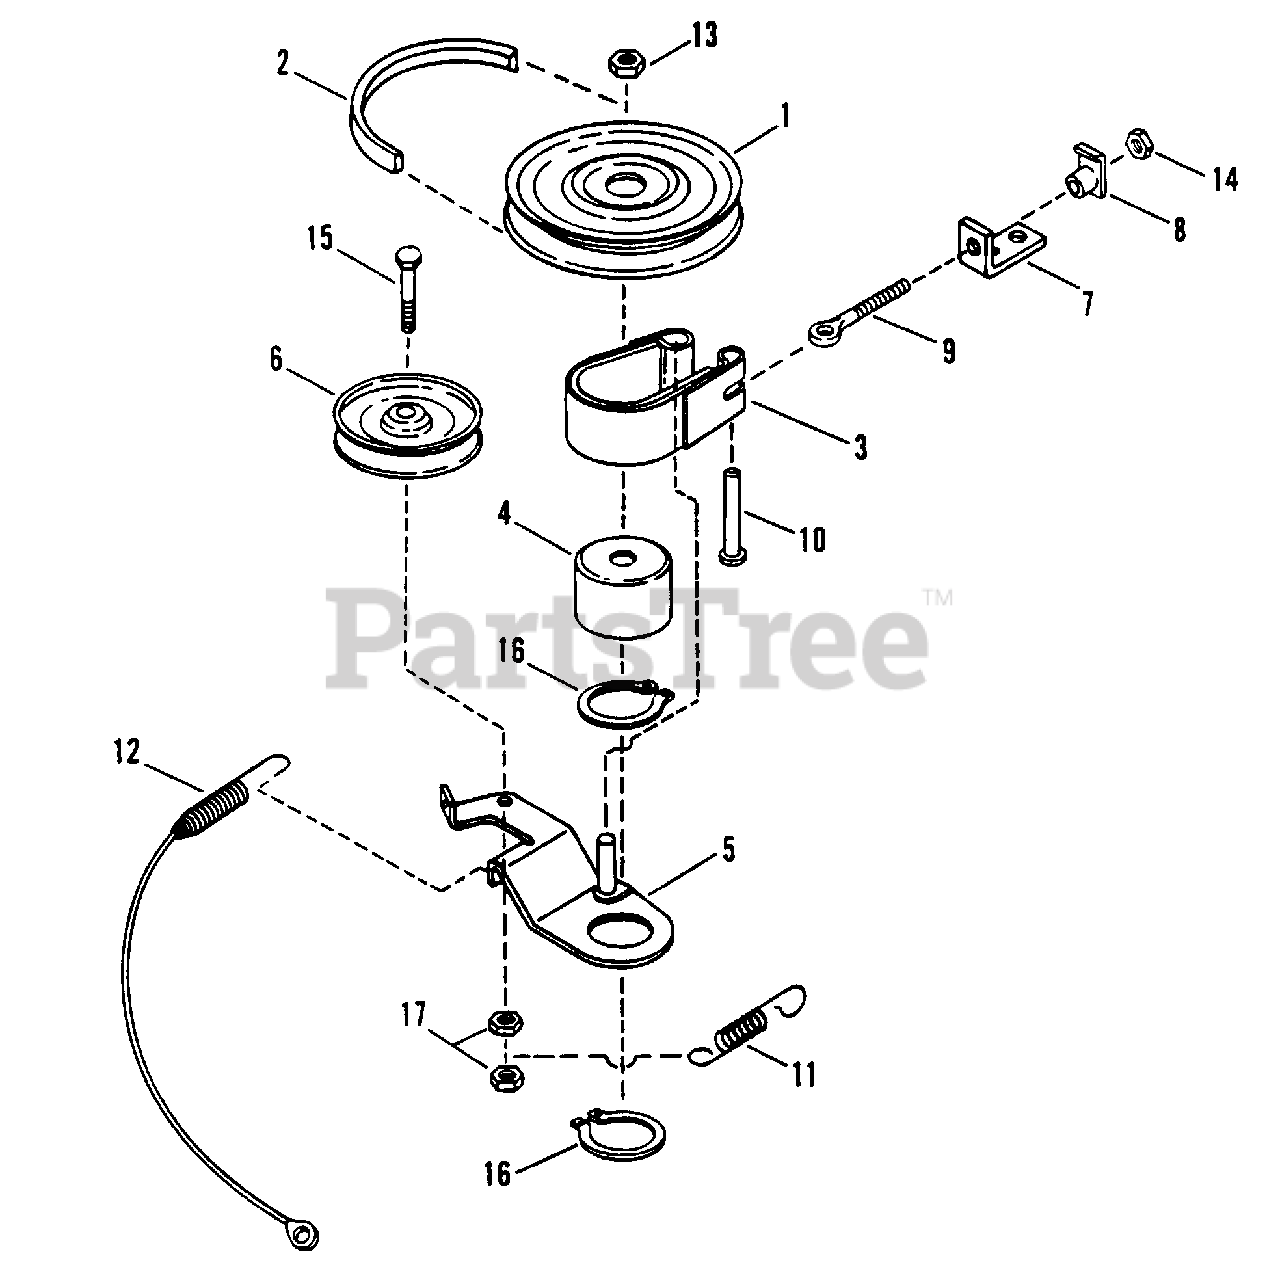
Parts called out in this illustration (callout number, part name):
1	PULLEY, Drive
2	BELT, Drive
3	BAND, Brake Assembly
4	DRUM, Brake
5	ASSEMBLY, Brake Arm
6	PULLEY, Idler
7	ANCHOR, Brake
8	TEE-NUT, 1/4-20
9	BOLT, 1/4-20 Eye
10	PIN, Clevis, 1/4 x 1 1/4"
11	SPRING, Blade Brake
12	CABLE, Blade
13	NUT, 3/4-16 Hex Jam
14	NUT, 1/4-20 Hex
15	SCREW, 3/8-24 x 2" Hex Hd. Cap
16	RING, 2" External Retaining
17	NUT, 3/8-24 Hex Lock
